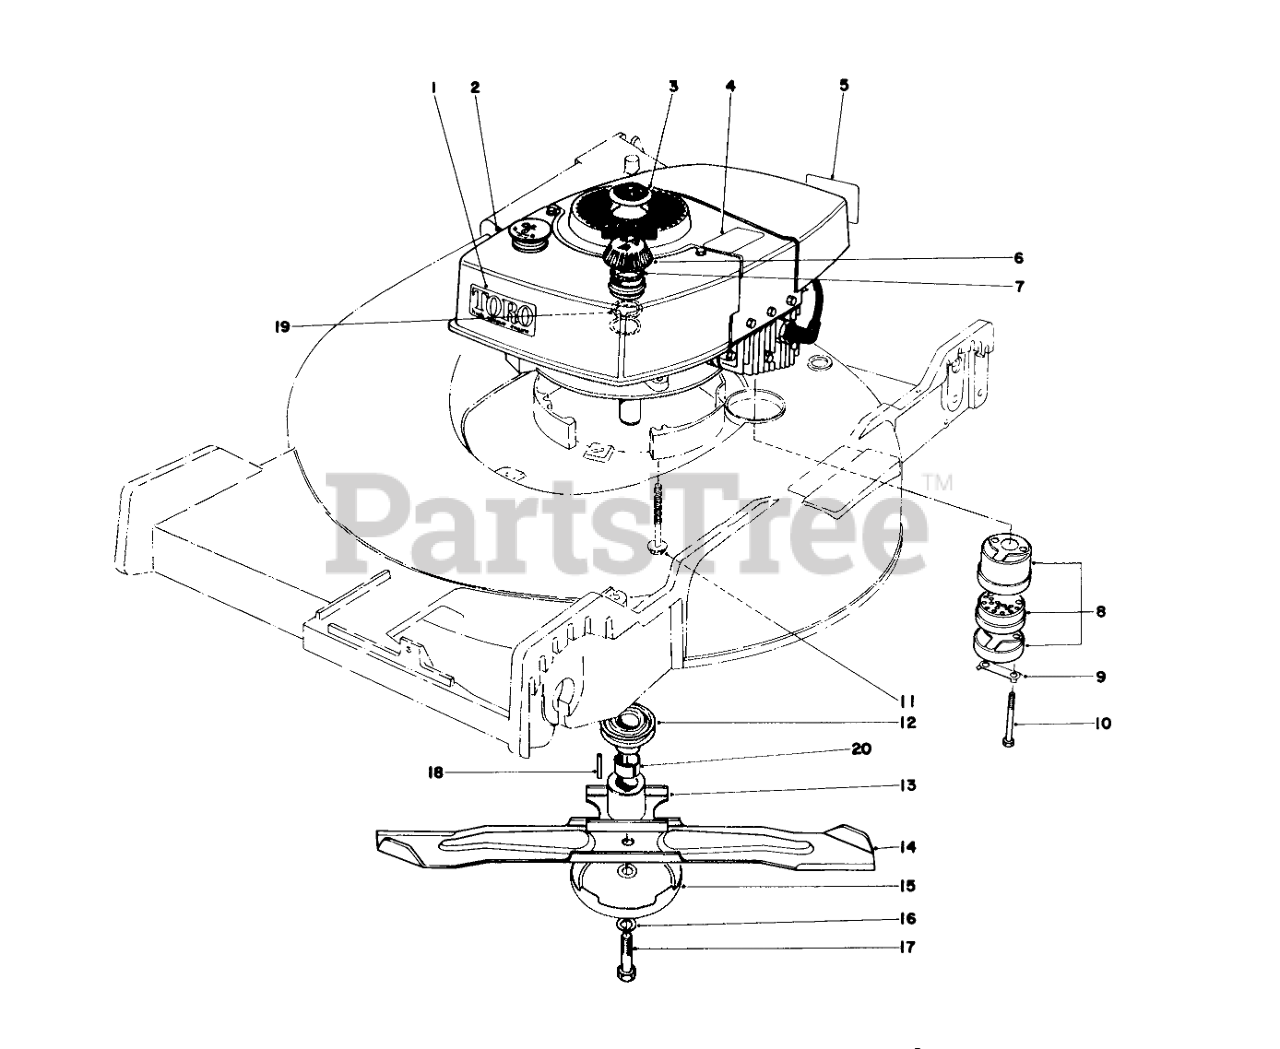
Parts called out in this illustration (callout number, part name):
1	High Torque
2	Engine
3	Plug Button
4	Decal Lockout
5	Decal Maintenance
6	Gas Cap Assembly (Incl. Ref. #7 & 19)
7	GASKET
8	Muffler Assembly (Incl. Ref. #9 & 10)
9	CLIP - LOCKING
10	SCREW-HH
11	3/8-16 X 2-3/4 CAPSCR
12	PULLEY DRIVER
13	BLADE RETAINER WA
14	Blade
15	Anti-Scalp Cup
16	WASHER-LOCK
17	BLADE SCREW
18	KEY-SQUARE
19	GAS CAP BAFFLE
20	Pulley Spacer
